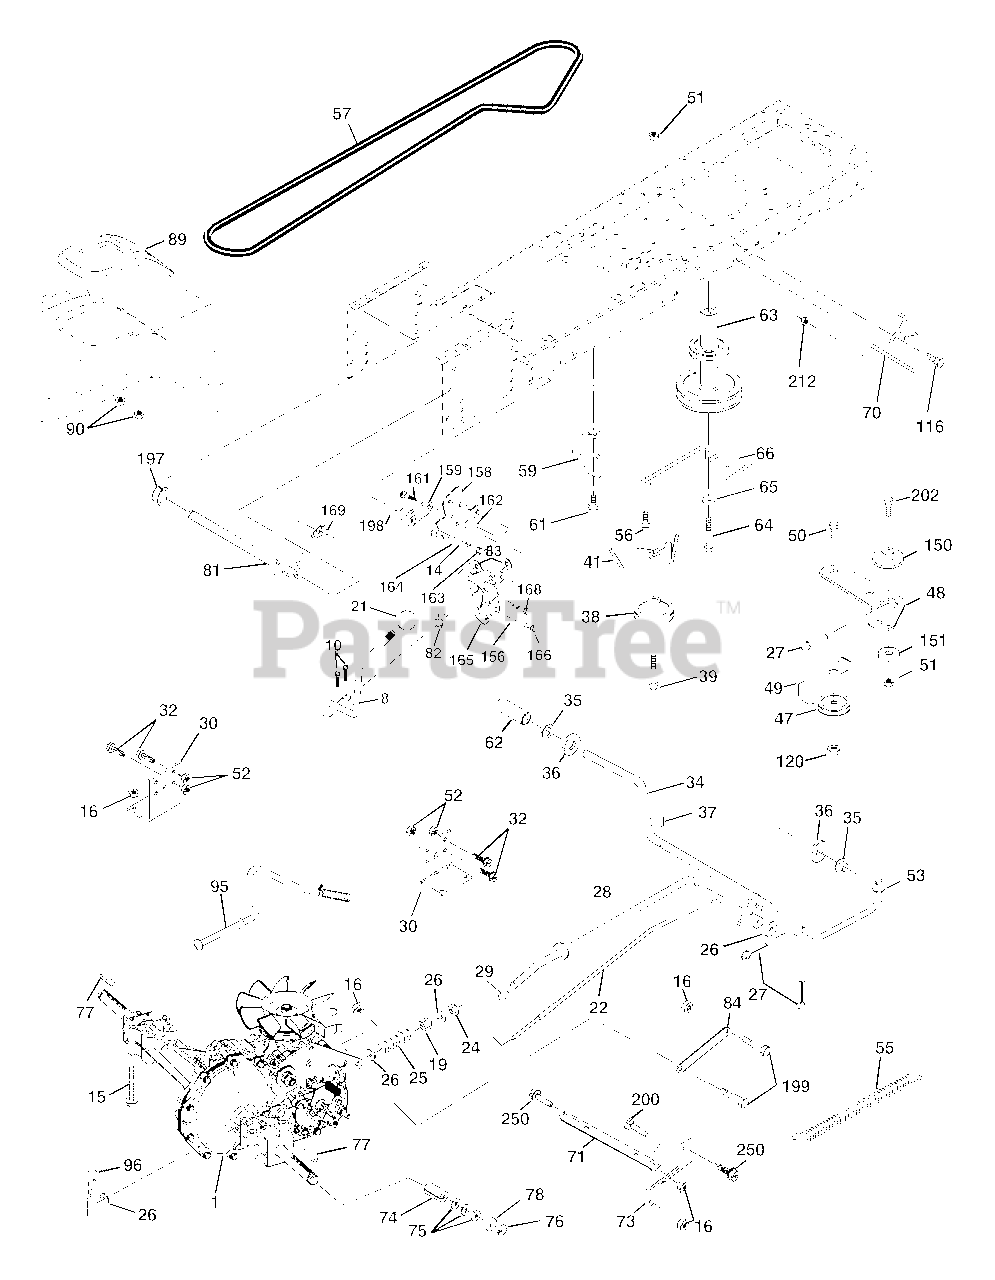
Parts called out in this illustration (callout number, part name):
10	Pin, Cotter 1/8 x 1
14	Washer Lock 1/4
15	Bolt Hex Flghd 5/16-18 Gr. 5
16	Nut, Lock Hex w/Ins 5/16-18 UNC
19	Nut, Lock Hex w/Wsh 3/8-16 UNC
21	Knob Rd. 1/2-13 Plstc. Thds. Blk.
22	Rod, Brake
24	Nut
25	Spring, Rod, Brake
26	Washer 13/32 x 13/16 x 16 Ga.
27	Pin, Cotter 1/8 x 3/4
28	Rod, Parking Brake
29	Cap, Parking Brake
30	Bracket, Transmission
32	Bolt Hex 5/16-18 UNC x 3/4
34	Shaft, Foot Pedal
35	Bearing, Nylon
36	Washer
37	Pin, Roll
38	Pulley, Idler, Composite
39	Bolt
41	Keeper, Belt, Idler
47	Pulley, Idler, V-Belt
48	Bellcrank Clutch Grnd Drustl
49	Retainer, Belt
50	Bolt 3/8-16 x 1-1/2 Gr. 5
51	Nut
52	Nut Crownlock 5/16-28
53	Link, Clutch
55	Spring, Return, Clutch
56	Screw 3/8-16 x 1-1/4
57	V-Belt, Drive
59	Keeper, Belt, Center
61	Screw, 3/8-16 x .875
62	Cover, Pedal
63	Pulley, Engine
64	Bolt Hex 7/16 x 4 Gr. 5
65	Washer
66	Keeper, Belt Engine Hydro
69	Screw Hex Wsh Hi-Lo 1/4-1/2 Unc
70	Guide, Belt, Mower Drive RH
71	Strap, Torque, Lh
73	Strap, Torque, Rh
74	Spacer, Axle
75	Washer 25/32 x 1-1/4 x 16 Ga.
76	Ring, E
77	Key, Square
78	Washer 25/32 x 1-5/8 x 16 Ga.
81	Shaft Asm Cross
82	Spring, Torsion
83	Washer 17/32 x 3/4 x 16 Ga.
84	Link Transaxle
89	Console, Shift
95	Control Asm Bypass Hydro
96	Spring, Retainer 1"
103	Nut, Hex Jam Toplock 1/2-20 UNF
116	Bolt 3/8-16 x 1
120	Bolt Hex 3/8-16 x 1-1/2
150	Spacer Retainer
151	Washer 13/32 x 2 x 10
156	Washer 5/16 x 1.0 x 1.25
158	Bracket Shift Mount
159	Hub Tapered Flange Shift
161	Bolt Rdhd Sqnk 1/4-20 x 3/4 Gr. 5
162	Nut Crownlock 1/4-20 Unc
163	Bolt Hex Fin 1/4-20 x 1
164	Washer 5/8 x .281 x 10 Ga.
165	Bracket Pivot Lever
166	Screw 5/16 x 1.0 x .125
168	Bolt Shoulder 5/16-18 x .561
169	Plate Fastening LT
197	Nyliner Snap-in 5/8" ID
198	Washer Nyl 7/8ID x .105" HYD
199	Bolt Shoulder 5/16-18 Unc
200	Bolt Rdhd Sqnk 5/16-18 Unc x 1
202	Bolt 3/8-16 x 1-3/4 Gr 5
205	Washer 17/32 x 1 x 16 Ga
212	Nut Hex Flange Lock
250	Screw 3/8-16 x .75
